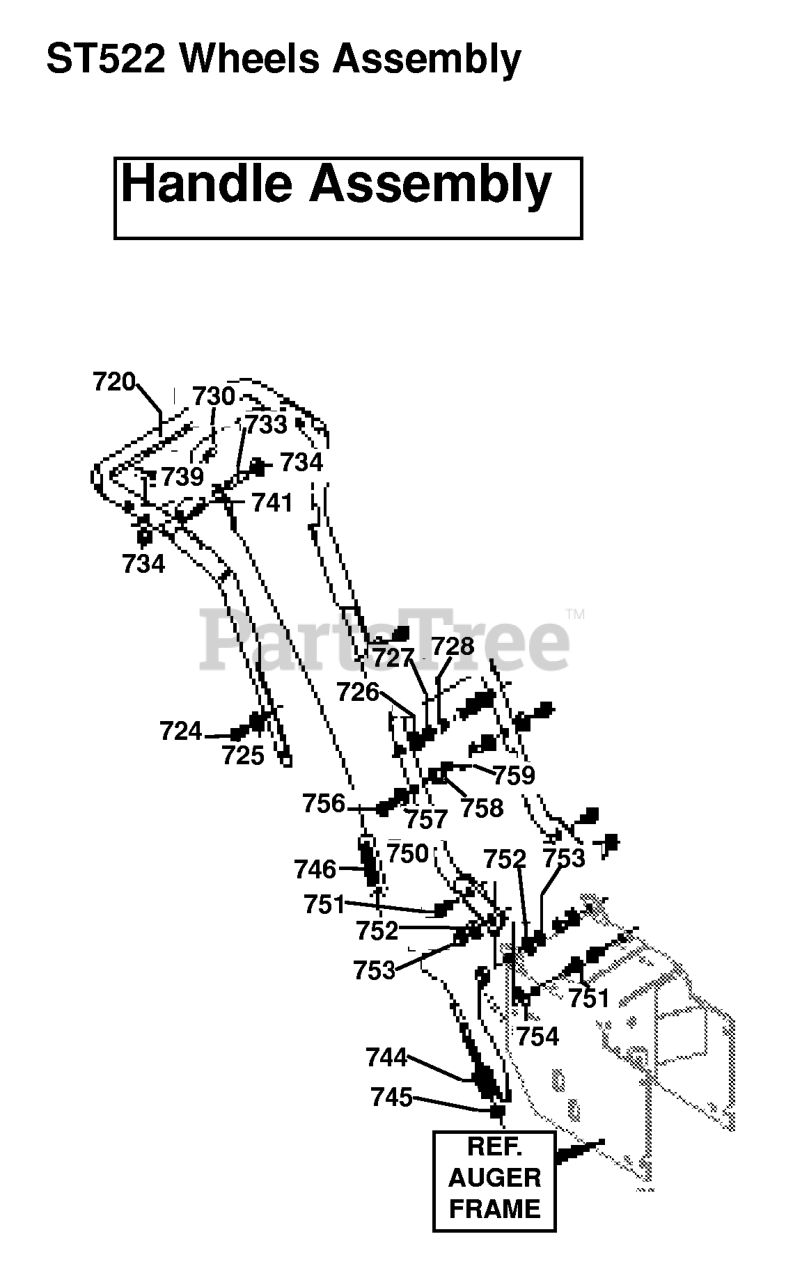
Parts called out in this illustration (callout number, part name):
720	Axle, .50 x 20"
725	WASHER, FLAT .344X .69X.
726	WASHER, HVSPTLK .328X.60X
727	NUT, 5/16-18 REGHEX
728	STOP, RED PLASTIC
730	Kit for Handle, Assy RH
733	CLUTCH PIN
734	NUT, PUSH ON CAP .312 OD
741	CABLE, CLUTCH
744	CLUTCH SPRING
746	BOOT, CLUTCH SPRING
750	HANDLE, LOWER
751	SCREW, 5/16-18X1.00 HHC
752	WASHER, HVSPTLK .328X.60X
753	NUT, 5/16-18 REGHEX
754	PUSHNUT, 5/16 BOLT RETAIN
756	SCREW, 5/16-18X2.00
757	WASHER, FLAT .344X .69X.
758	WASHER, HVSPTLK .328X.60X
759	NUT, 5/16-18 REGHEX
